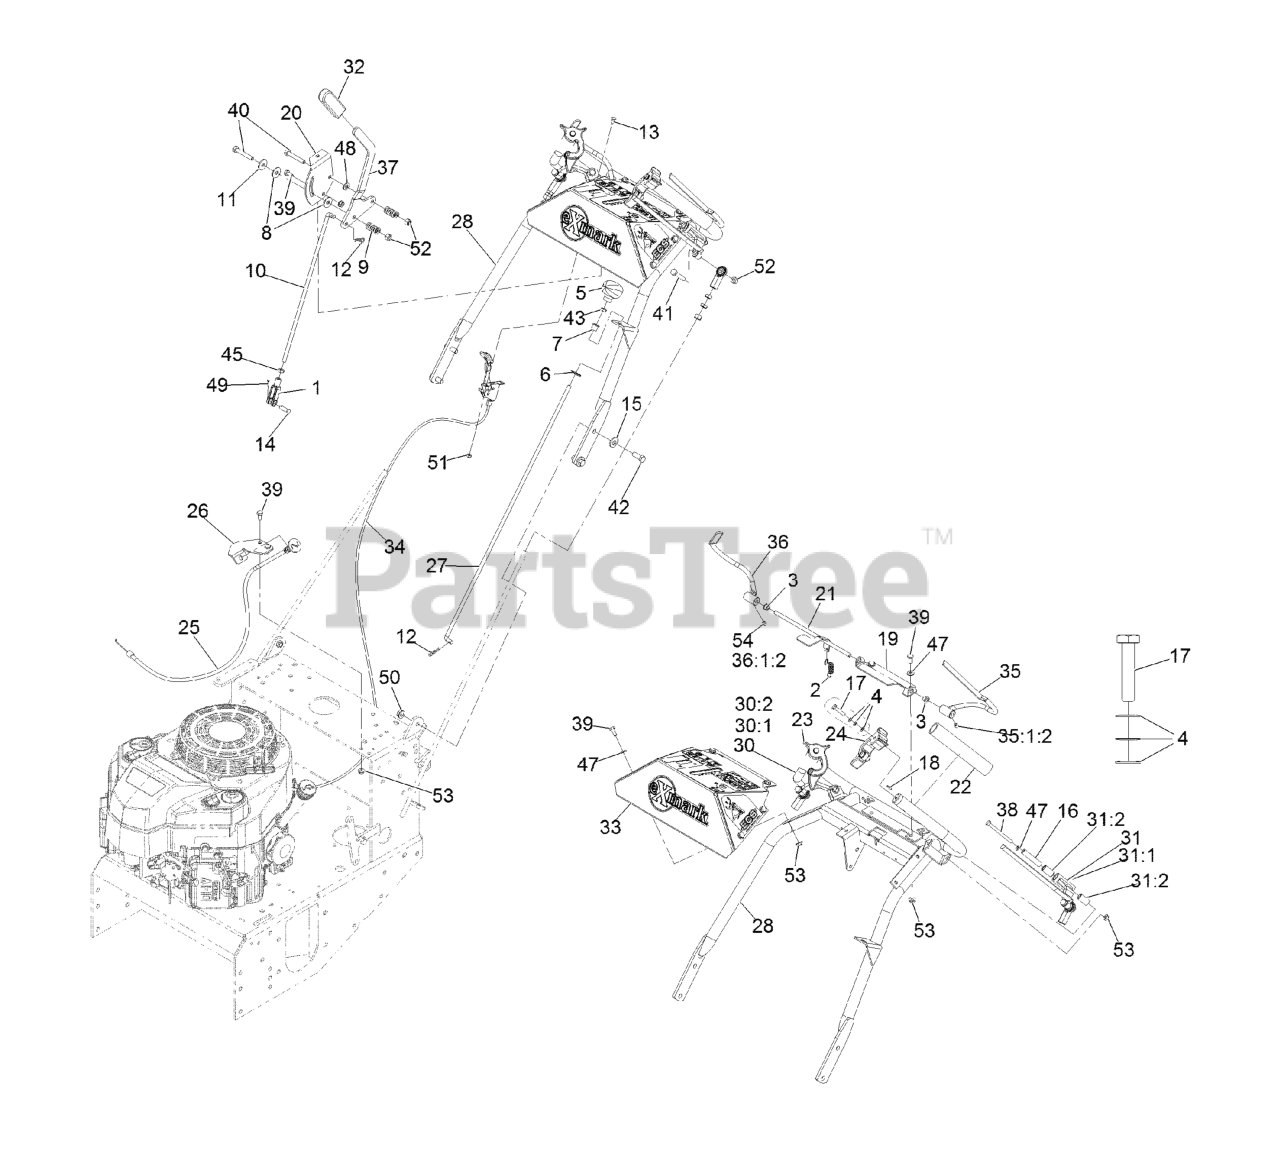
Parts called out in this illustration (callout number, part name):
1	YOKE-ADJUSTABLE
2	SPRING-EXTENSION
3	BUSHING-NYLON
4	WASHER-SPRING
5	KNOB-PUSH / PULL
6	NUT-PUSH
7	BEARING-NYLON
8	WASHER-FRICTION
9	SPRING-COMPRESSION
10	ROD-CONTROL, SPEED
11	WASHER-FRICTION
12	PIN-COTTER
13	BOLT-CARR
14	PIN-CLEVIS
15	WASHER-BELLEVILLE
16	BUSHING-LEVER, DRIVE
17	SCREW-HH
18	PIN-SPRING
19	BRACKET,OPC AXLE
20	BRACKET,SHIFTER SLIDE (PLTD)
21	WLD,OPC LEVER AXLE
22	GRIP-BAR, HANDLE
23	ASM,LATCH RH THUMB
24	ASM,LATCH LH THUMB
25	CABLE-CHOKE
26	BRACKET-CABLE, CHOKE
27	LINKAGE,BLADE PUSH/PULL
28	WLD,VH ECS HANDLE
30	DRIVE LEVER-ASM, RH
30:1	WLD,RH DRIVE LEVER
30:2	BUSHING, SLEEVE
31	DRIVE LEVER-ASM, LH
31:1	WLD,LH DRIVE LEVER
31:2	BUSHING, SLEEVE
32	GRIP-HANDLE, STEERING
33	ASM,CONSOLE W/DECALS
34	CONTROL, THROTTLE
35	WLD,LH OPC LEVER
35:1:2	SCREW-SET
36	WLD,RH OPC LEVER
36:1:2	SCREW-SET
38	SCREW-HH
39	SCREW-HH
40	SCREW-HH
41	SCREW-HH
42	SCREW-HH
43	NUT-JAM
45	NUT-JAM
47	WASHER-FLAT
48	WASHER-PLAIN
49	PIN-COTTER
50	NUT-HHF, WHIZ
51	NUT-LOCK, NI
52	NUT-LOCK, NI
54	SCREW-SET
